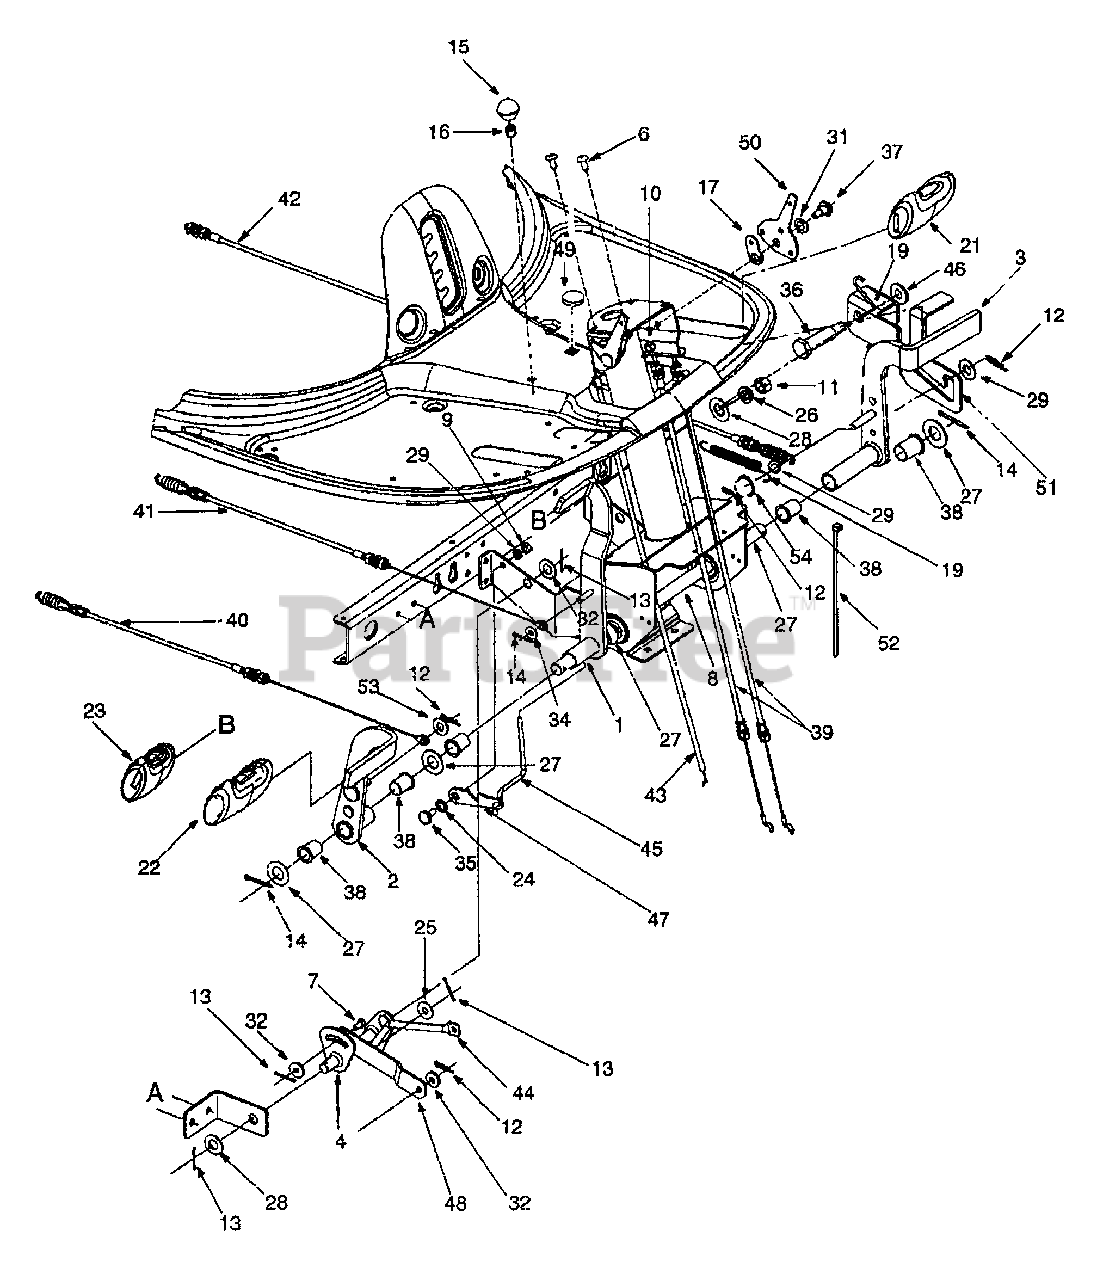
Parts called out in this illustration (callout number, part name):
7	Clevis Pin
9	Hex Nut 1/4-20
10	Lock Nut 1/4-20
11	Hex Nut 3/8-16
12	Internal Cotter Pin
13	Hairpin Clip
14	Hairpin Clip
16	Snap-on Bushing
19	Torsion Spring
24	Flat Washer 3/8 X .620 X .033
28	Flat Washer .510 X 1.00 X .060
29	Flat Washer .406 x 1.25 x .10
31	Spring Washer
32	Flat Washer
34	Flat Washer .271 X .630 X .065
35	Shoulder Screw 375 Dia X .18
36	Shoulder Screw
37	Shoulder Screw .375 X .380 X 1/4-20
38	Flange Bearing
39	Shift Cable
40	Variable Drive Cable
41	Brake Cable
42	Deck Cable
43	Throttle Choke Cable: 67"
44	Brake Rod
45	Brake Lock Out Rod
46	Shoulder Spacer
53	Flat Washer.406 I.D. x 875 O.D.
